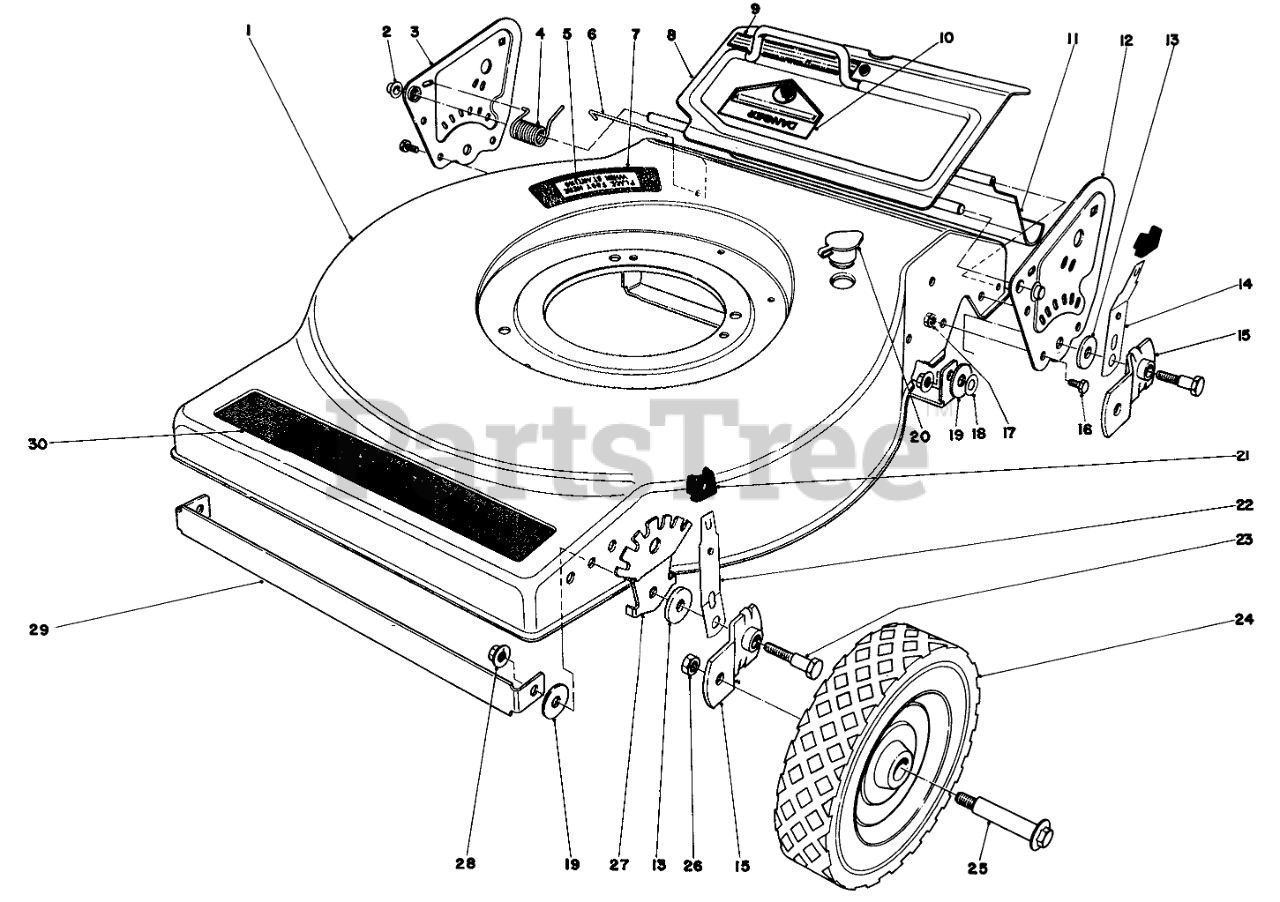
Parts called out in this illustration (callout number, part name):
1	Housing
2	RETAINER-PUSH ON
3	Side Plate R.H.
4	TORSION SPRING
5	Decal Step Pad
6	SHIELD ROD
7	PAD STEP
8	Rear Door
9	Decal-Door
10	DECAL-DANGER
11	SAF SHIELD REAR
12	Side Plate L.H.
13	PIVOT WASHER
14	Spring Arm
15	PIVOT ARM ASM A
16	SCREW-HH
17	NUT-LOCK, CONE
18	WASHER-PLAIN
19	WASHER
20	WASHOUT PLUG
21	KNOB-ARM
22	SPRING ARM ASM
23	PIVOT SCREW
24	Wheel Assembly
26	Nut
27	Quadrant
29	DECK SUPPORT
30	Decal-Deck
